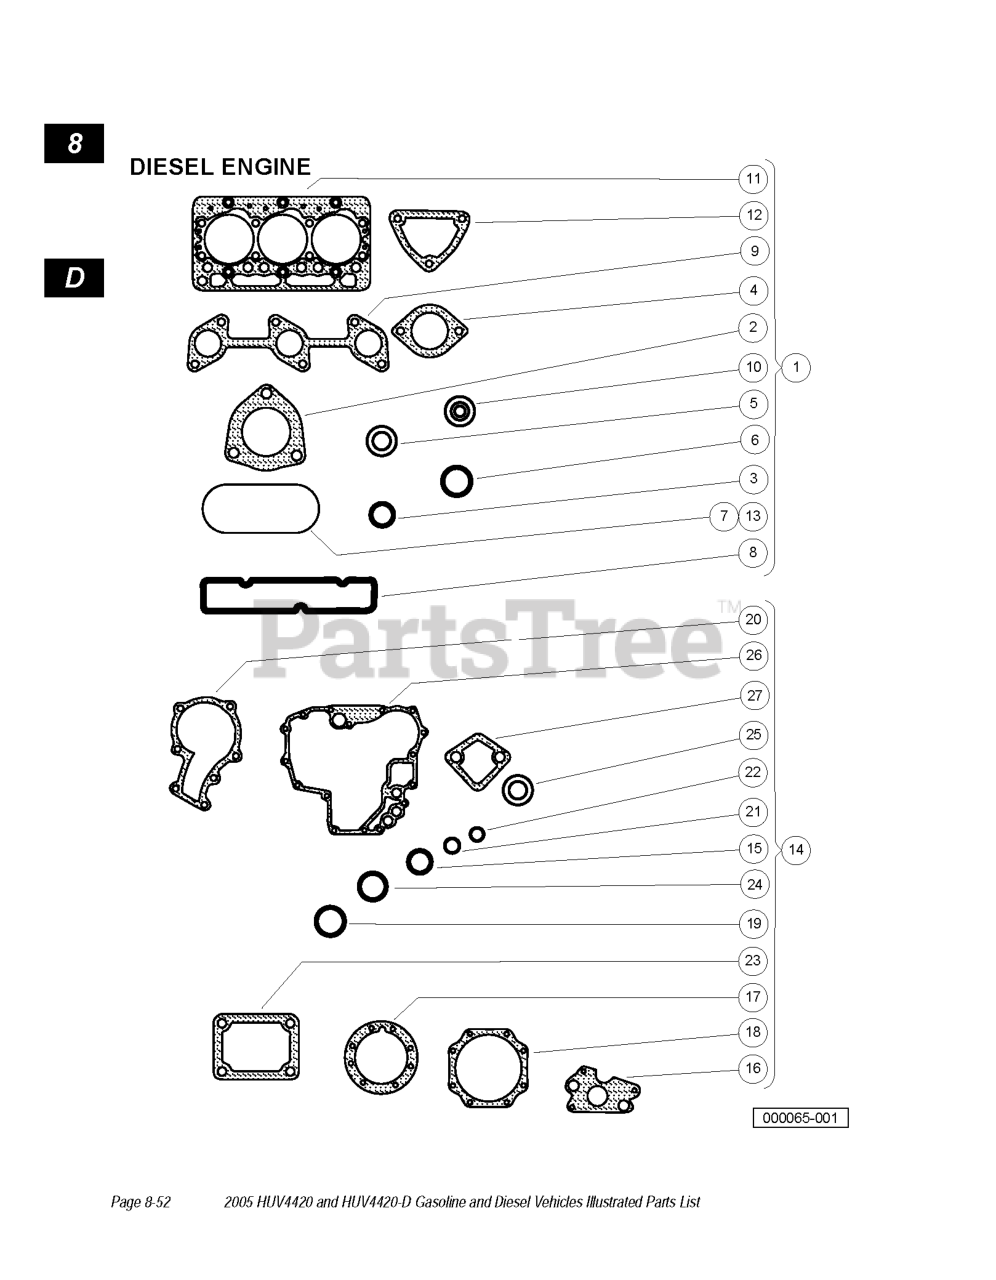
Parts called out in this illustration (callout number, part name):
1	KIT, GASKET UPPER, D722
2	GASKET, EXHAUST DIESEL
3	O-RING, 8 X 7
4	GASKET, THERMOSTAT
5	GASKET, 6X10
6	O RING, 30X36
7	GASKET, HEAD COVER
8	GASKET, IN-MANIFOLD
9	GASKET, EX-MANIFOLD
10	SEAL, VALVE STEM
11	GASKET, CYLINDER HEAD
12	GASKET, WATER FLANGE
13	GASKET-HEAD COVER
14	KIT, GASKET LOWER, D722
15	O-RING, 18 X 13
16	GASKET, OIL PUMP NA
17	GASKET, BEARING CASE
18	GASKET, COVER
19	O RING, 23X26
20	GASKET, WATER PUMP, D722
21	O RING, 19X16
22	O RING, 9X7
23	GASKET, CONTROL PLATE
24	O RING, 20 X 17
25	GASKET, IDLE APPARATUS, REAR
26	GASKET, GEARCASE, D722
27	GASKET, FUEL PUMP, D722
